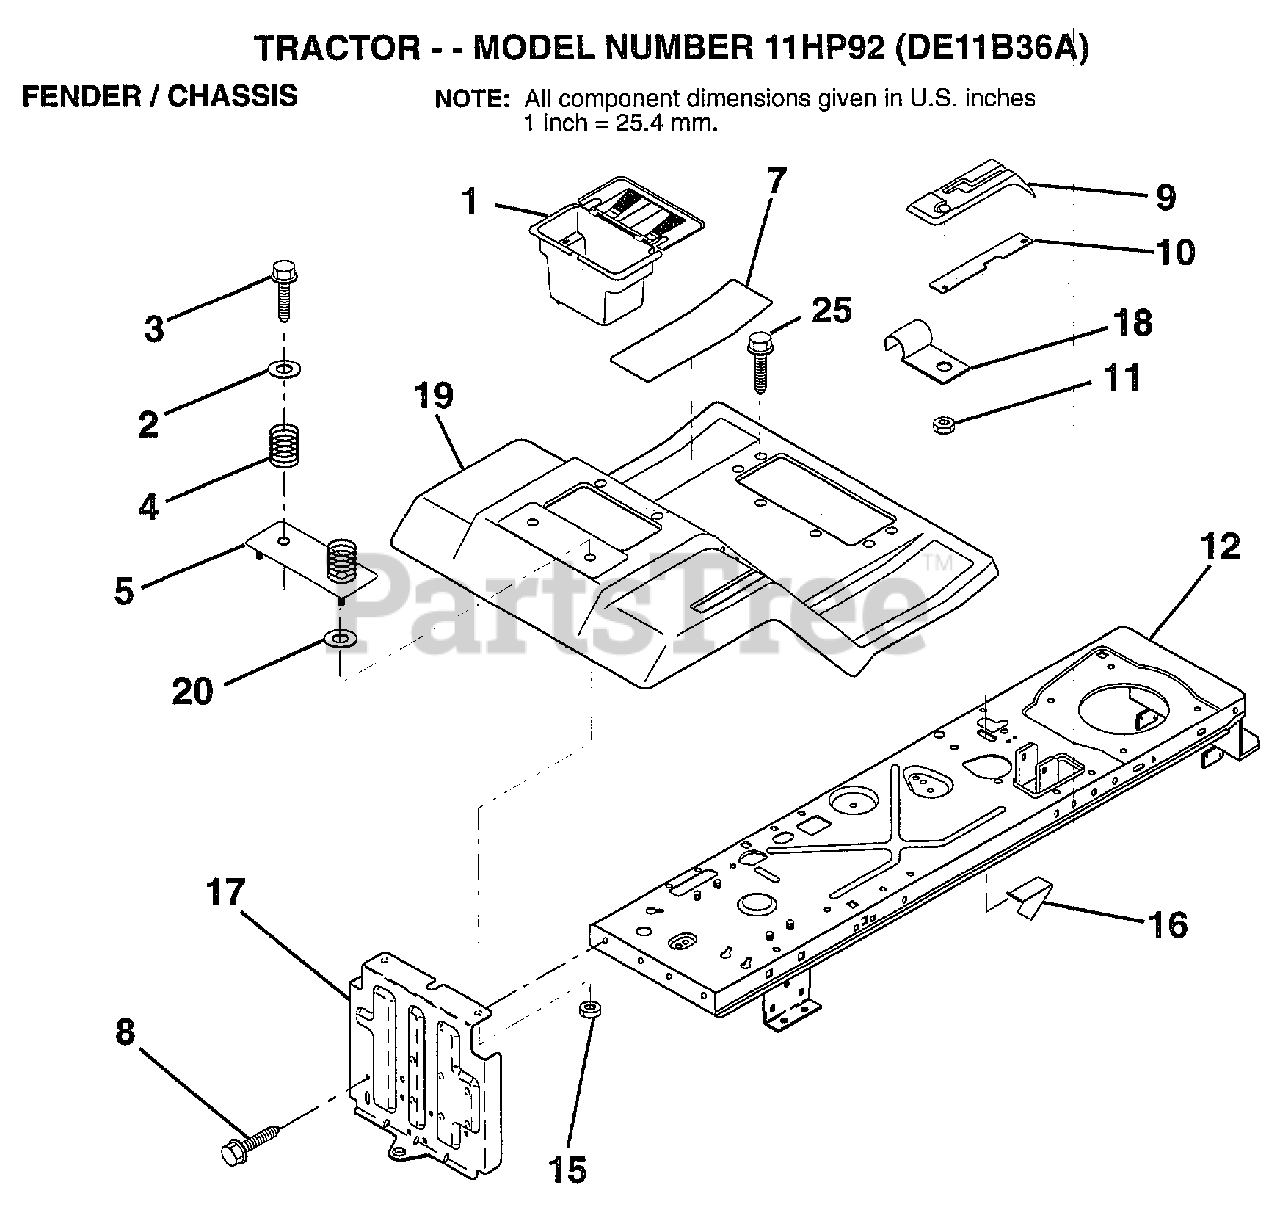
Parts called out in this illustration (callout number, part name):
1	"CASE,BATTERY.MECH"
2	WASHER
3	SCREW
4	SPRING COMPRESSIO
5	PLATE, BATTERY
7	PAD FOOTREST
8	SCREW
9	CONSOLE.SHT.4SP.
10	PLATE LOCK SHIFT
11	NUT
12	CHASSIS.WELD.ASM.
15	NUT HXKEP 1/4X20
17	DRAWBAR ASM LR
18	"CLIP,INSULATOR"
19	FENDER.FOOTREST
25	SCREW TAPPING
